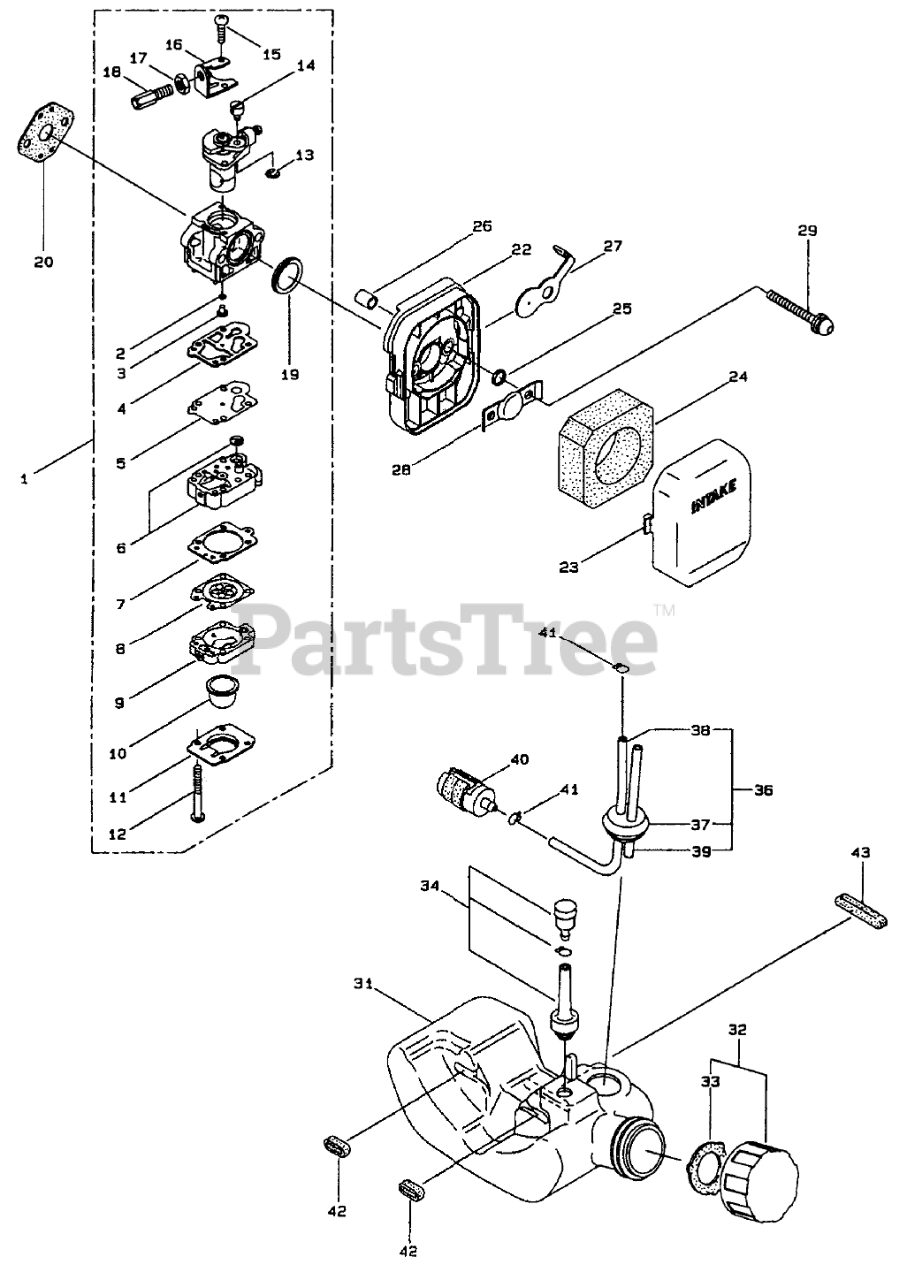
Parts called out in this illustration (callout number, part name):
1	Carburetor Assembly (Incl. Ref. # 2-19)
2	O-RING
3	JET - MAIN #41.5
4	GASKET (NC)
5	PUMP - DIAPHRAGM (NC)
6	PUMP - BODY (NC)
7	GASKET (NC)
8	ASM - DIAPHRAGM
9	PURGE - BODY (NC)
10	PRIMER
11	PLATE - COVER (NC)
12	SCREW (NC)
13	E-RING
14	SWIVEL
15	Screw
16	BRACKET
18	ADJUSTER
19	PACKING
20	GASKET
22	HOUSING
23	COVER
24	ELEMENT
25	WASHER
26	SLEEVE
27	VALVE - CHECK
28	PLATE
29	CAPSCREW
31	TANK - FUEL
32	Fuel Tank Cap Assembly (Incl. Ref. # 34)
33	PACKING
34	ASM - BREATHER
36	Fuel Pipe Assembly (Incl. Ref. # 38-40)
37	GROMMET
38	PIPE - FUEL
39	PIPE - RETURN
40	ASM - FUEL FILTER
